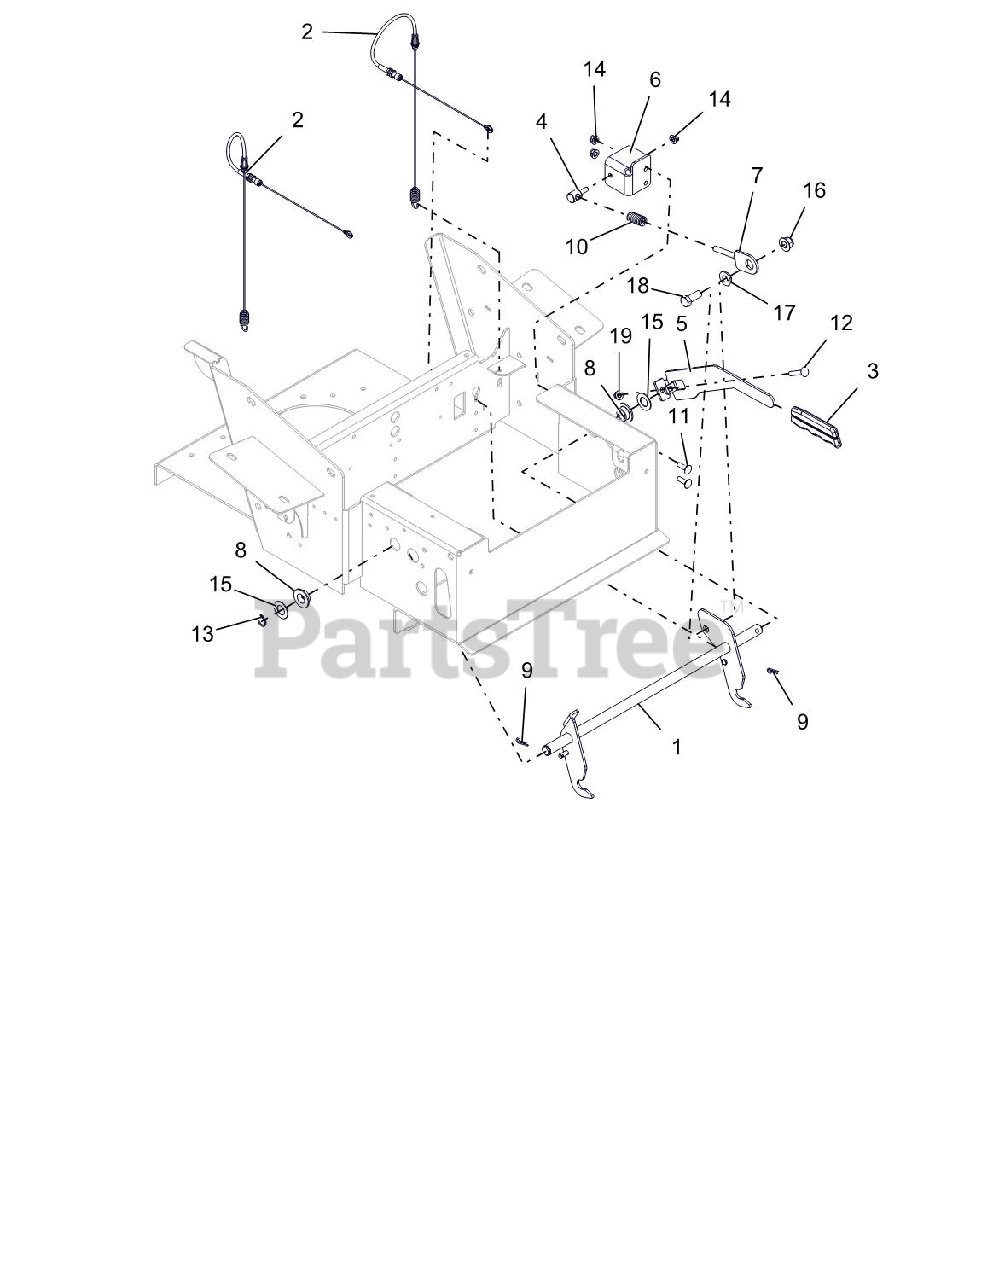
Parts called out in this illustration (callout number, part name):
1	WLDMT, PT/PT100 BRAKE LEVER (BLACK)
2	CABLE, BRAKE
3	GRIP, PARKING BRAKE (YELLOW)
4	TRUNNION, .31-18
5	HANDLE, PT/PT100 BRAKE (BLACK)
6	BRACKET, TRUNNION MTG
7	WLDMT, BRAKE
8	BSHG, FLANGE .762 X 1.48 X .44 NYLON
9	PIN, HAIR INT .08X.18X1.18 YWZC
10	SPRG, COMPRESSION
11	BOLT, CARRIAGE 0.3125-18X1 GR5
12	BOLT, CARRIAGE 0.3125-18X1.75 GR5
13	RG-RTNG-EXT .750x.078
14	NUT-LK-NYL-FLG .31-18 YWZC
15	WSHR-FL-STL .755X1.375X.062 YWZC
16	NUT-LK-NYL-FLG .50-13 YWZC
17	BSHG, FLANGE .515X.750X.31X1.12
18	BOLT, HEX 0.5-13X1.25 GR5
19	NUT, LK-CTR-FLG .31-18 YWZC
